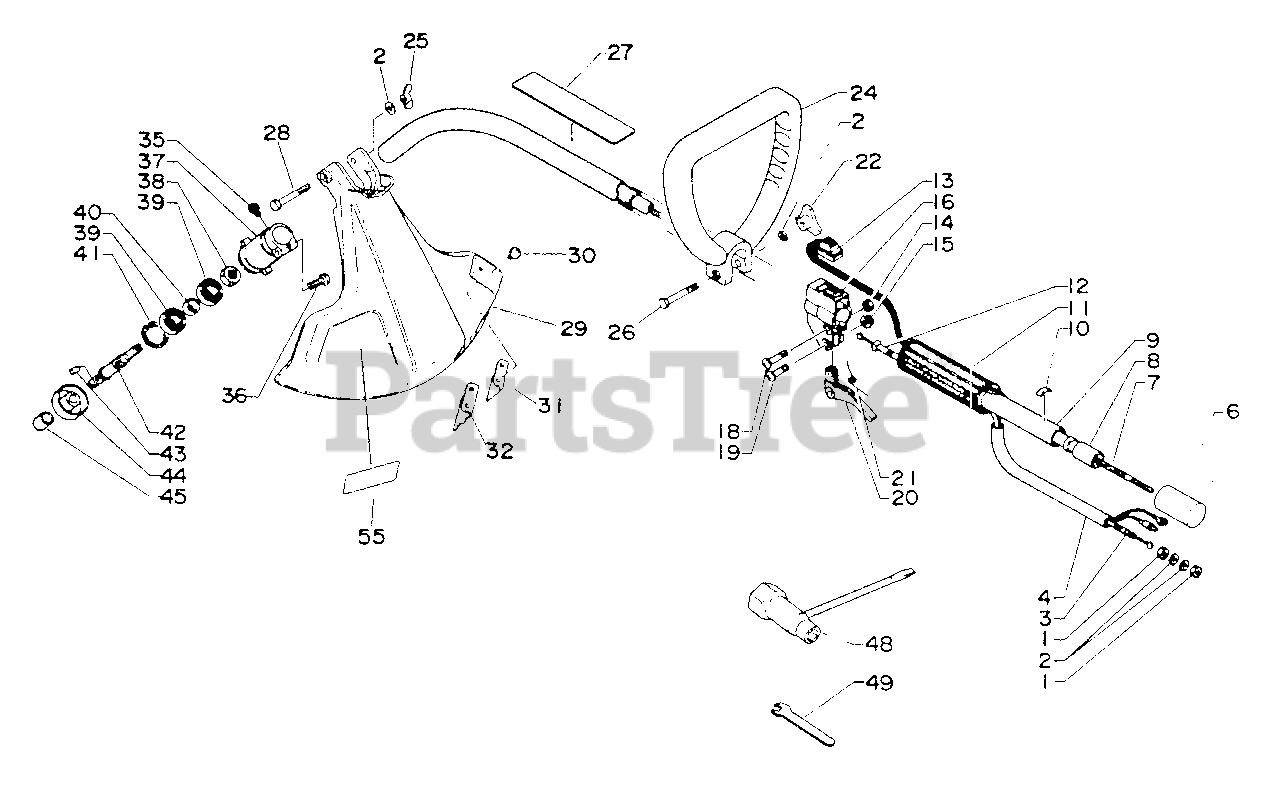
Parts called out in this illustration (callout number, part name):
2	WASHER 6.5×11.5×0.8
3	CABLE, THROTTLE
7	DRIVESHAFT - FLEXIBLE
8	BUSHING
9	PIPE, MAIN
10	LABEL - ALIGNMENT
11	GRIP, HANDLE
12	GUIDE, CABLE
13	IGNITION SWITCH ASSY
14	NUT M5
15	LOCKNUT - 5
16	BRACKET, THROTTLE
18	SCREW 5×28
20	TRIGGER, THROTTLE
21	SPRING, THROTTLE
22	KNOB, FASTENER
24	HANDLE
25	NUT, WING 6
26	BOLT - 6×40
27	LABEL - CAUTION
28	BOLT - 6×50
29	SHIELD
30	SCREW 5×16
31	KNIFE, TRIMMER LINE
32	PROTECTOR
35	SCREW 4×10
36	BOLT - 5×25
37	CASE, GEAR
38	NUT 12 L.H.
39	BEARING, BALL 6001 DDU
41	RING, SNAP 28
42	SHAFT, GEAR
44	PLATE, ADAPTER - UPPER
48	WRENCH
55	LABEL, ECHO
